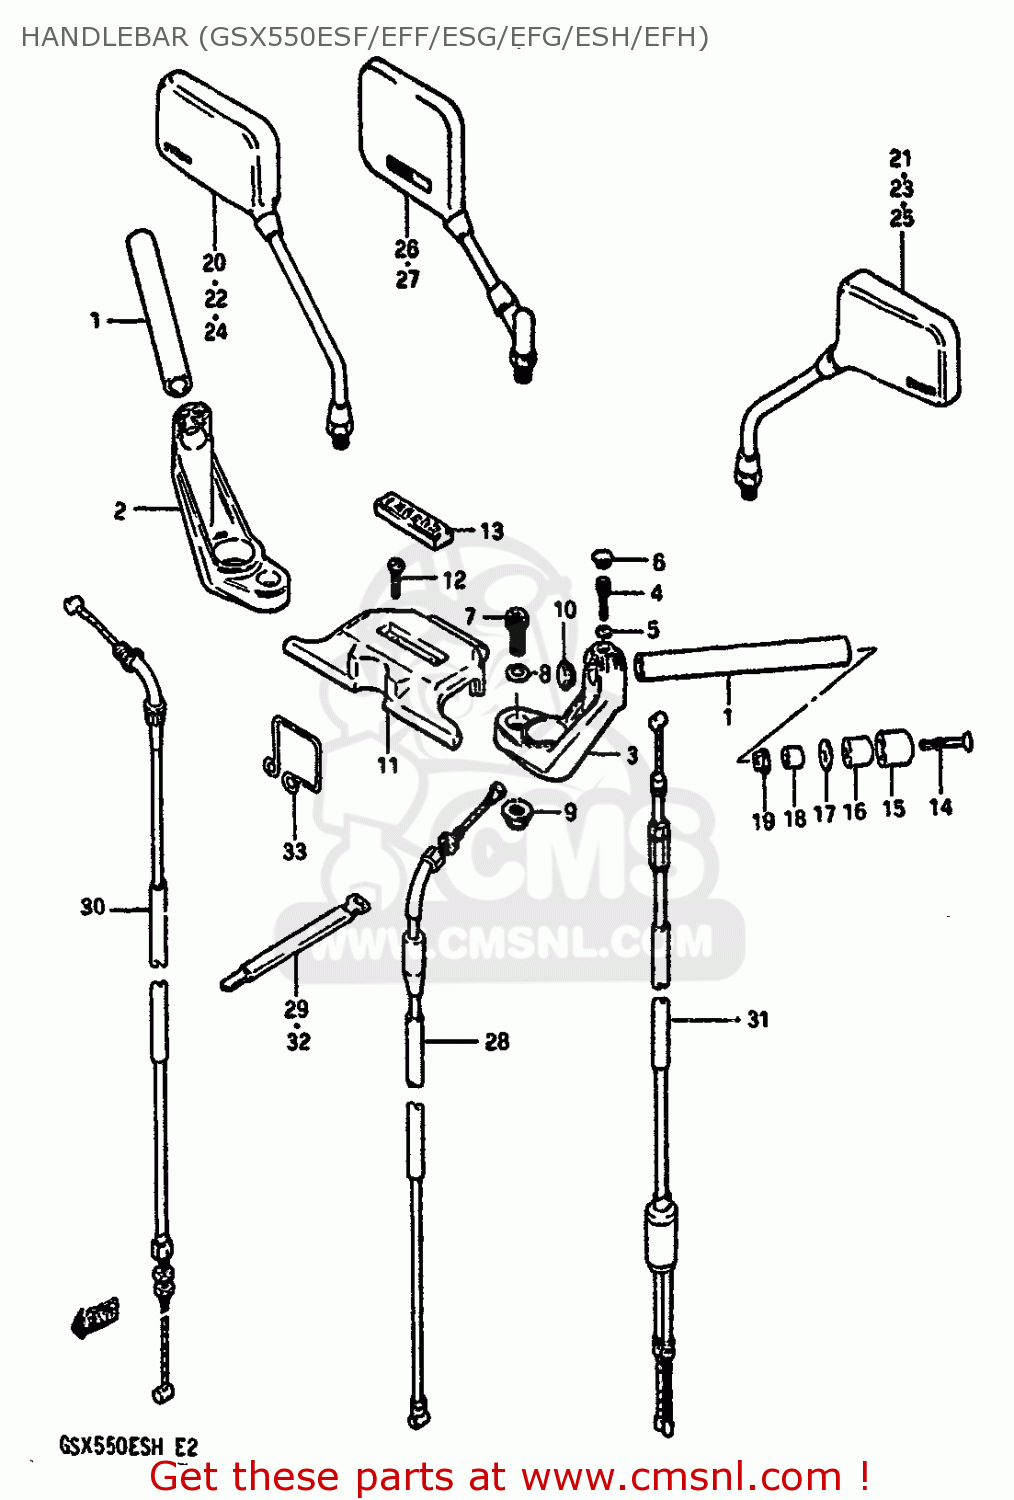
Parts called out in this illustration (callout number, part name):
1	HANDLEBAR
2	HOLDER,HANDLEBAR,RIGHT
3	HOLDER,HANDLEBAR,LEFT
4	BOLT 8X35
5	WASHER
6	CAP(OD:14.5)
7	BOLT(10X50)
8	WASHER
9	NUT 10MM
10	CAP,GRIP END
11	PAD,HANDLEBAR
12	SCREW
13	EMBLEM,HANDLE PAD
14	SCREW 6X55
15	CAP,BALANCER
16	BALANCER,HANDLEBAR
17	SPACER,BALANCER
18	EXPANDER,BALANCER
19	NUT
20	MIRROR ASSEMBLY,REAR VIEW
21	MIRROR ASSEMBLY,REAR VIEW
22	MIRROR,REAR VIEW RH
23	MIRROR,REAR VIEW LH
24	MIRROR,REAR VIEW RH
25	MIRROR,REAR VIEW LH
26	MIRROR ASSEMBLY,REAR VIEW
27	MIRROR ASSEMBLY,REAR VIEW
28	CABLE ASSY,CLUTCH
29	CLAMP
30	CABLE ASSY,THROTTLE
31	CABLE COMP,STARTER
32	CLAMP
33	GUIDE,CABLE/HARNESS
